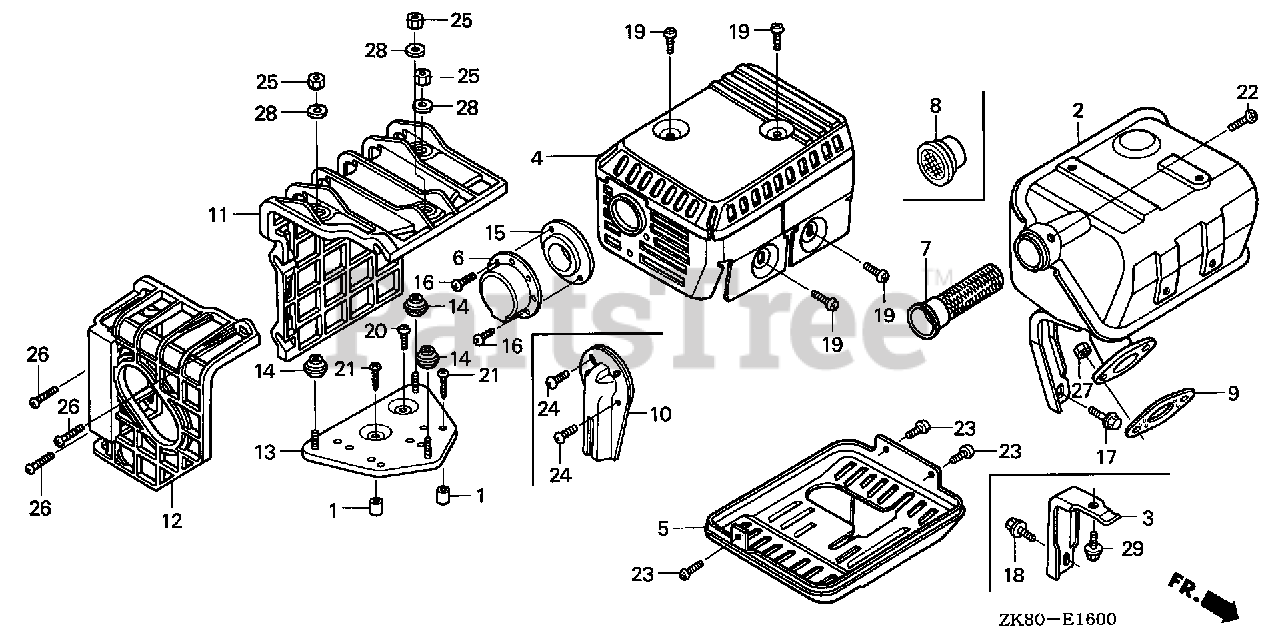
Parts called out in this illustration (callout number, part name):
2	MUFFLER (STD)
2	MUFFLER (ARRESTER)
4	PROTECTOR, MUFFLER (STD) (BLACK)
7	ARRESTER, SPARK
9	GASKET, MUFFLER
19	SCREW, TAPPING (5X8)
22	SCREW, TAPPING (4X6)
27	NUT, HEX. (8MM)
